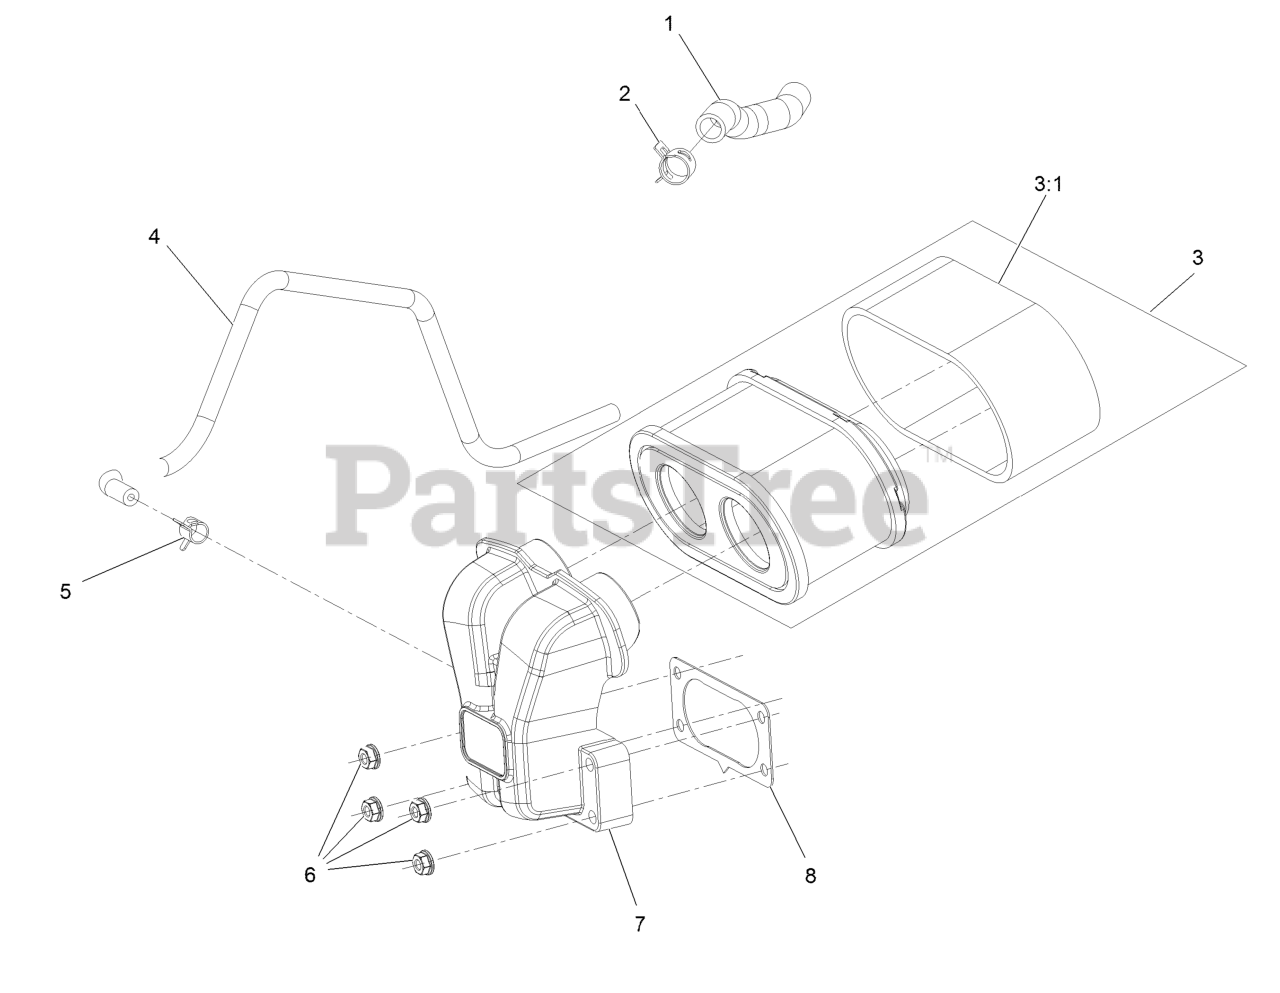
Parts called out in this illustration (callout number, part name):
1	Tube-Breather
2	Clamp-Hose
3	Air Filter Kit
3:1	Prefilter
4	Hose-Fuel
5	Clamp-Hose
6	Nut-Flange
7	Manifold-Filter, Air
8	Gasket-Carburetor
